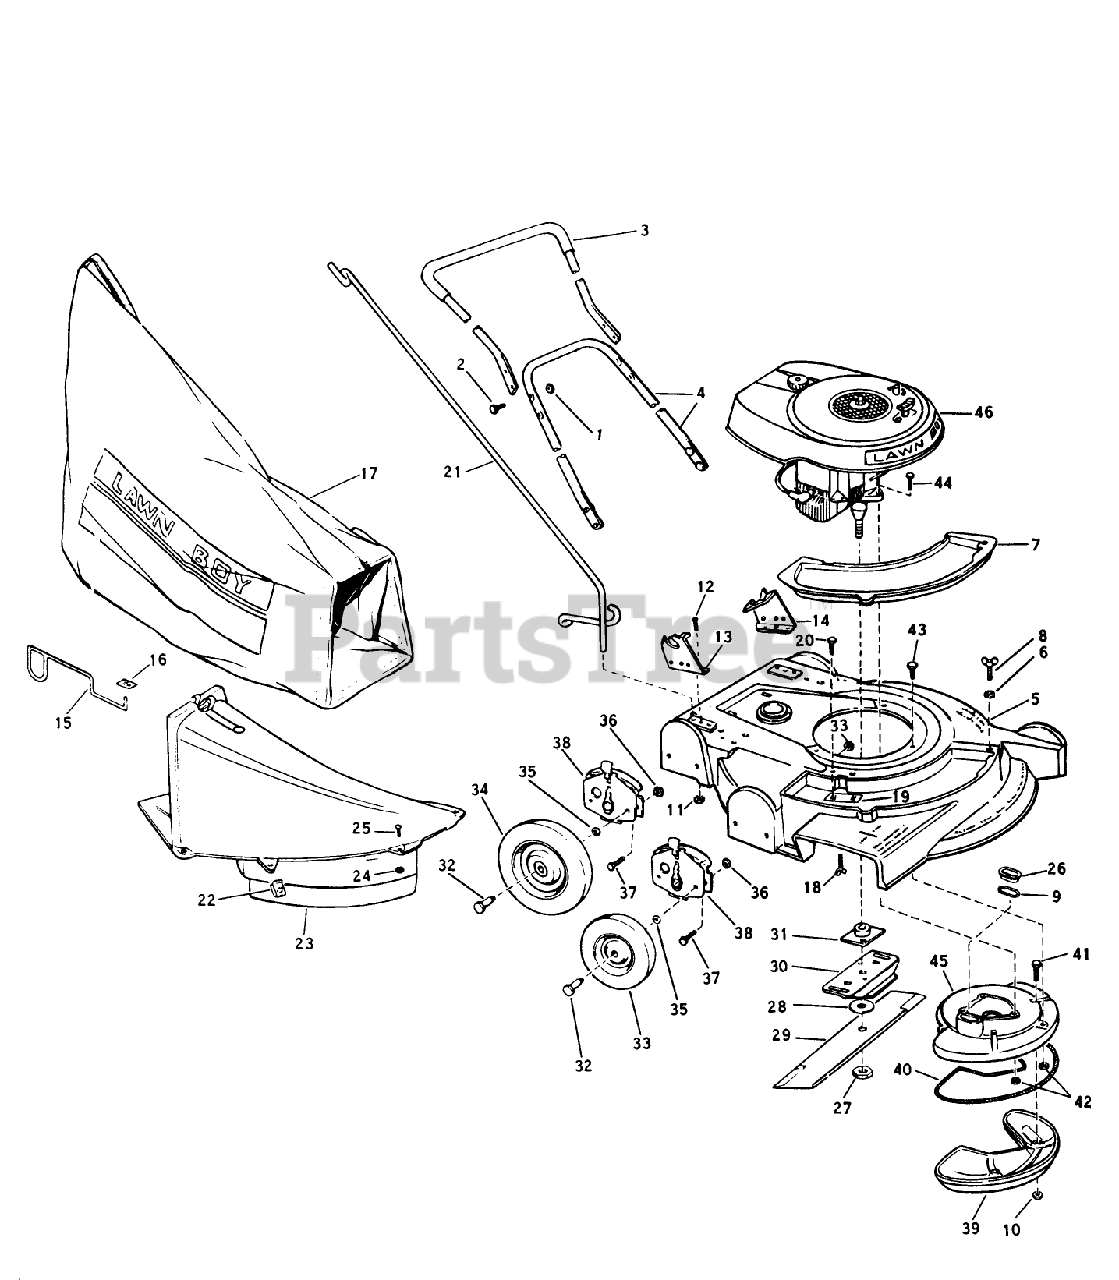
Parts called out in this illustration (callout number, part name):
3	Handle Grip Assy. Top
9	GASKET S
10	LOCKNUT E
12	SCREW S
17	89802 LB WHOLE GOODS
22	SPEED NUT ARDEN
23	Chute Skirt Assembly (Includes Hardware)
27	NUT-BLADE
31	PLATE AND COLLAR ASM
32	BOLT WHEEL
35	WASHER WROUGHT
